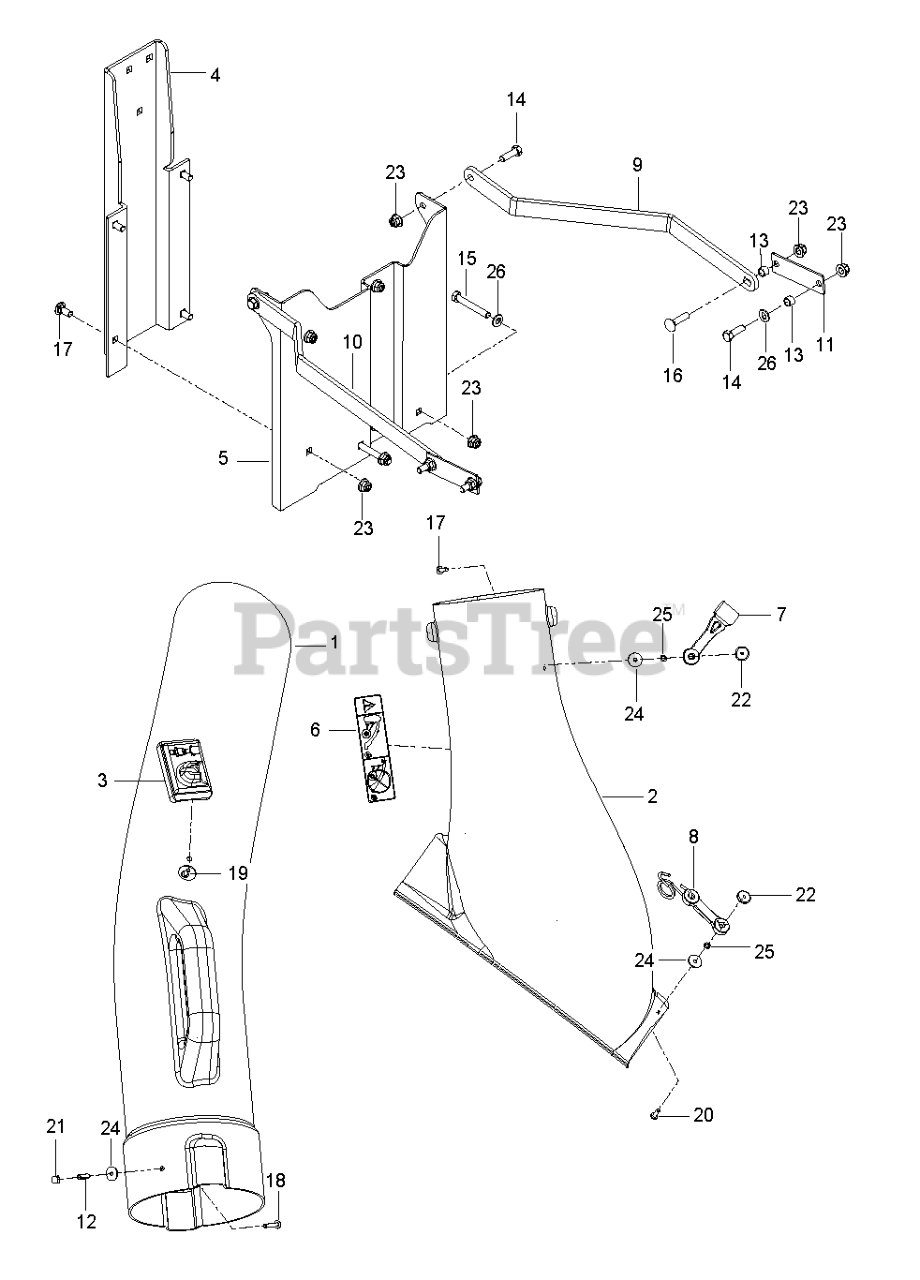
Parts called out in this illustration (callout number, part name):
1	CHUTE.UPPER.ZTR.FCS.42"
2	RP.CHUTE.LOWER.FCS 42"
3	DUMP BAG INDICATOR
4	BRACKET, COLLECTION BLK
5	BRACKET.LOWER.2 BIN BAGGER
6	DECAL, CATCHER
7	HOOD LATCH
8	LATCH ASSY TBR
9	STRAP.SUPPORT.RT.BLK
10	STRAP.SUPPORT.LT.BLK
11	REINFORCEMENT PLATE BLK
12	BSHG .202X.75 LG SPLIT ZD SPEC
13	SPACER,391"ID.375",L.078",WALL
14	HCS 5/16C X 1
15	BOLT.FIN HEX 5/16-18UNC X2 1/4
16	BOLT, CARRIAGE 5/16X1-1/4
17	BOLT 5/16C X 3/4" CARRIAGE
18	SCREW
20	SCREW
21	NUT 10-24 ACORN ZD
22	NUT 10-24 WELD PLATED
23	5/16-18 NYLOC FLANGE NUT
25	WASHER - 3/16 LOCK ZD
26	WASHER
